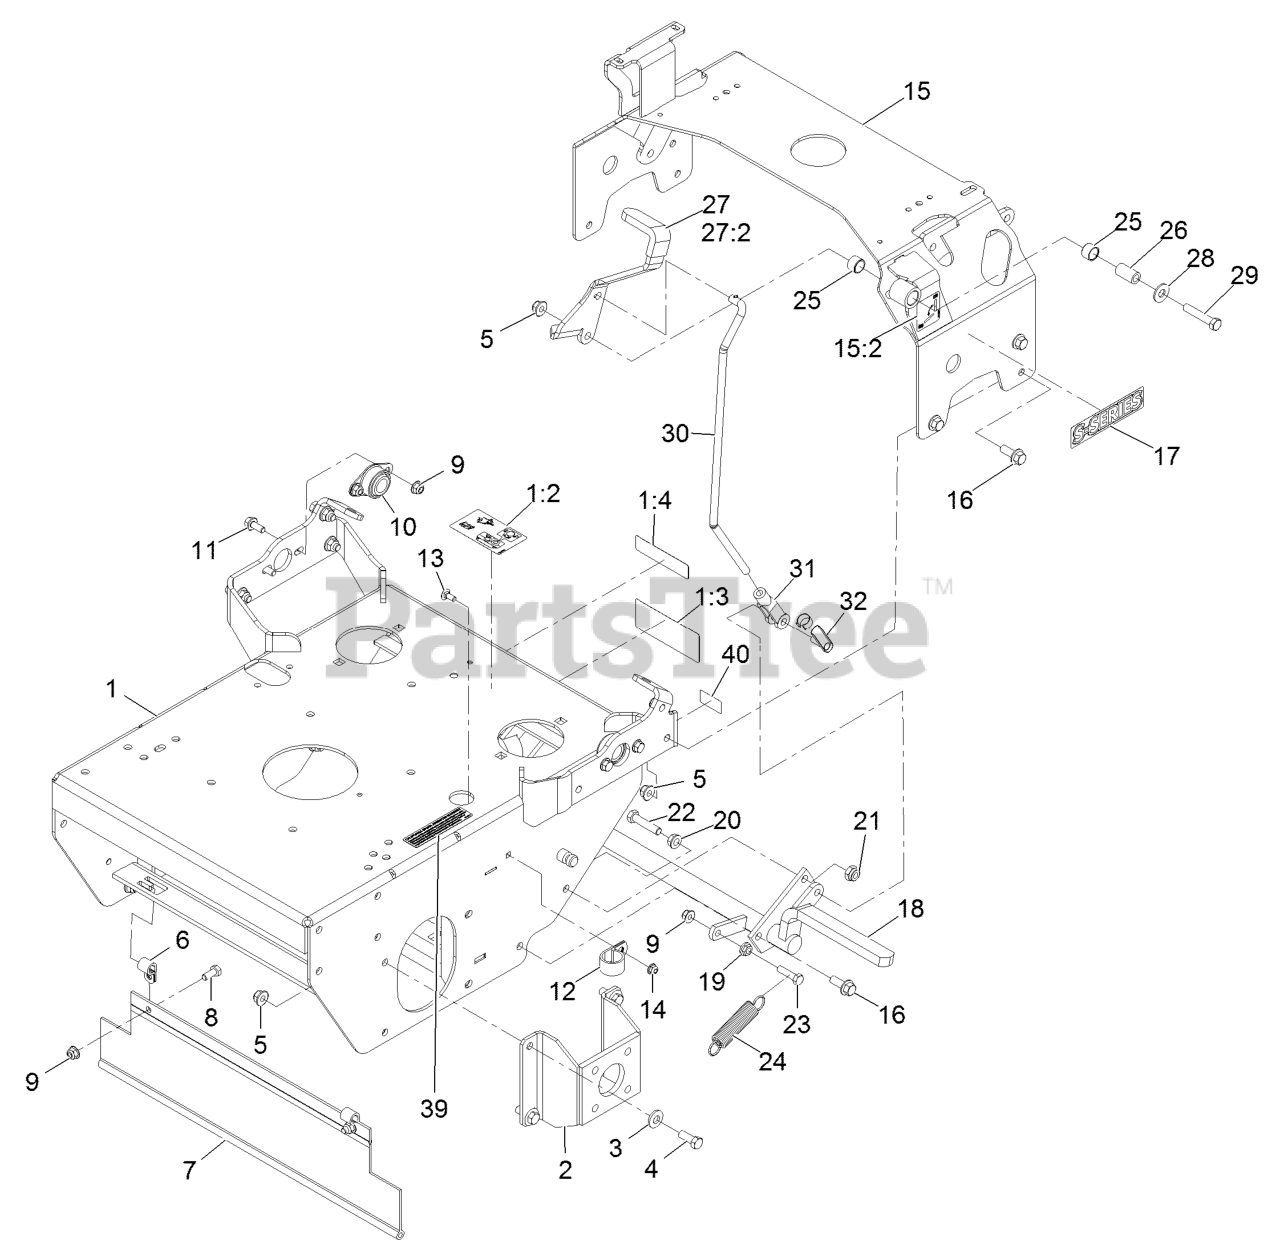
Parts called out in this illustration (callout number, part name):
1	ASM, ENGINE DECK W/ DECAL
1:2	DECAL-DRIVE RELEASE
1:3	DECAL-WARNING, SULKY
1:4	DECAL-WARNING
2	WLD,MOTOR MOUNT 48&52
3	WASHER-BELLEVILLE
4	SCREW-HH
5	NUT-HF, NI
6	CLIP-LOOM
7	SHIELD-DRAG
8	SCREW-HH
9	NUT-HF, NI
10	BEARING-FLANGE, SIDE
11	SCREW-HHF
12	CLIP-LOOM
13	SCREW-CARR
15	ASM, TANK SUPPORT W/ DECA
15:2	DECAL-PARK BRAKE, CE
16	SCREW-HHF 3/8-16 X 1
17	DECAL-S-SERIES
20	NUT-HHF, WHIZ
21	NUT-LOCK, NI
22	SCREW-HH
23	SCREW-HH
24	SPRING-IDLER
25	SLEEVE-BUSHING
26	BUSHING-PIVOT
27	ASM, BRAKE LEVER W/ GRIP
27:2	GRIP-LEVER
28	WASHER-FLAT
29	SCREW-HH
30	LINKAGE, BRAKE
31	YOKE-LINKAGE, BRAKE
32	PIN-SPRING, CLEVIS
39	DECAL-ARRESTER, SPARK
40	Decal-Patent Ttco.Com
